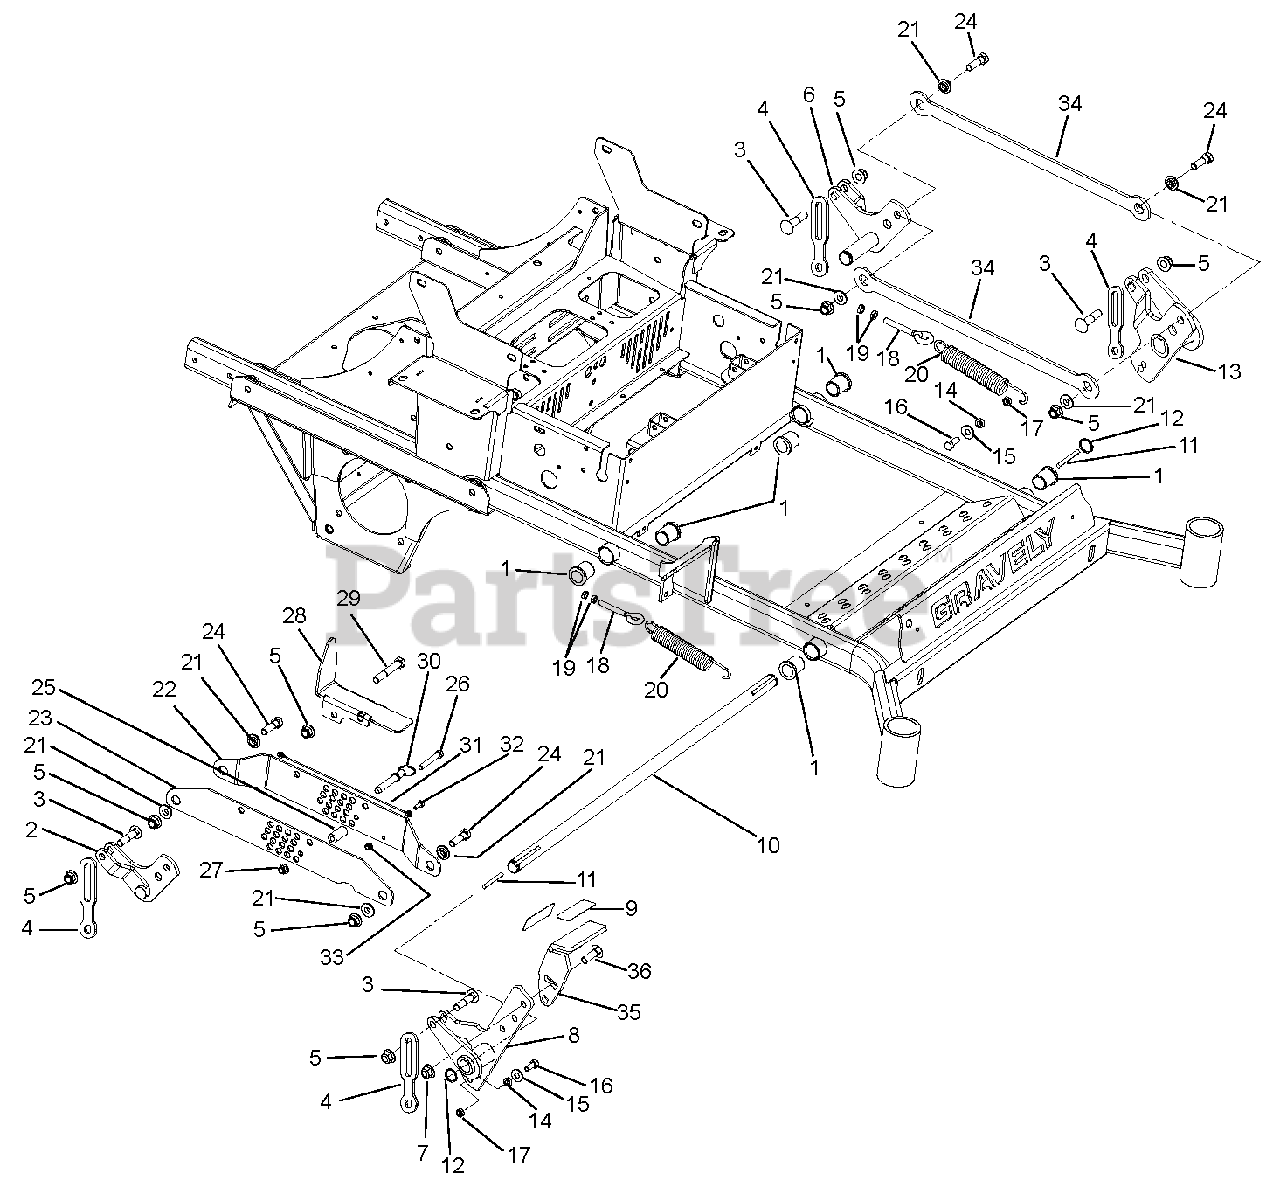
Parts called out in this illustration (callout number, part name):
1	Bushing, Flange 1.00 x 1.25 x 1.50 x 1.50
2	Weldment, Rear Deck Lift Right Hand
3	Bolt, Round Head Square Neck .50-13 x 2.25 G5YZ
4	Link, Deck Lift
5	Nut, Locking Nyloc Flange .50-13
6	Weldment, Rear Deck Lift Left Hand
7	Nut, Locking Nyloc Flange .50-13
8	Weldment, Deck Foot Lift
9	Grip Pedal 1.50 x 3.00
10	Shaft, Front Mower Lift
11	Key, Square .25 x 2.50 x .25 SAE
12	Ring, Retaining External 1.00 x .078
13	Weldment, Front Deck Lift Left Hand
14	Bushing, Sleave .377 x .624 x .235
15	Washer, Flat Steel .438 x 1.00 x .083
16	Bolt, Hex .38-16 x 1.00 Grade 5
17	Nut, Locking Center Jam .375-16
18	Bolt, Eye .375-16 x 2.50
19	Nut, Hex Jam .375-16
20	Spring, Tension .162 x 1.25 x 8.25 WLD 25
21	Bushing, Flange .515 x .750 x .395 x 1.120
22	Bracket, Lift/Cut Height Inboard Right Hand
23	Bracket, Lift/Cut Height Outboard Right Hand
24	Bolt, Hex .50-13 x 1.75 Grade 5
25	Spacer, .375 x .750 x 1.54
26	Bolt, Hex .38-16 x 2.50 Grade 5
27	Nut, Locking Nyloc Flange .38-16
28	Weldment, Mechnical Lock-Up
29	Bolt, Hex .50-13 x 3.25 Grade 5
30	Pin, .50 x 2.00
31	Cable, 12.0 Lanyard, Nylon
32	Bolt, Hex .25-20 x .75 Grade 5
33	Nut, Locking Nyloc Flange .25-20
34	Link, Lift
35	Adjustable Foot Lift Pedal, Black
36	Bolt, Round Head Square Neck .50 x 13 x 1.50 Grade 5 YZ
